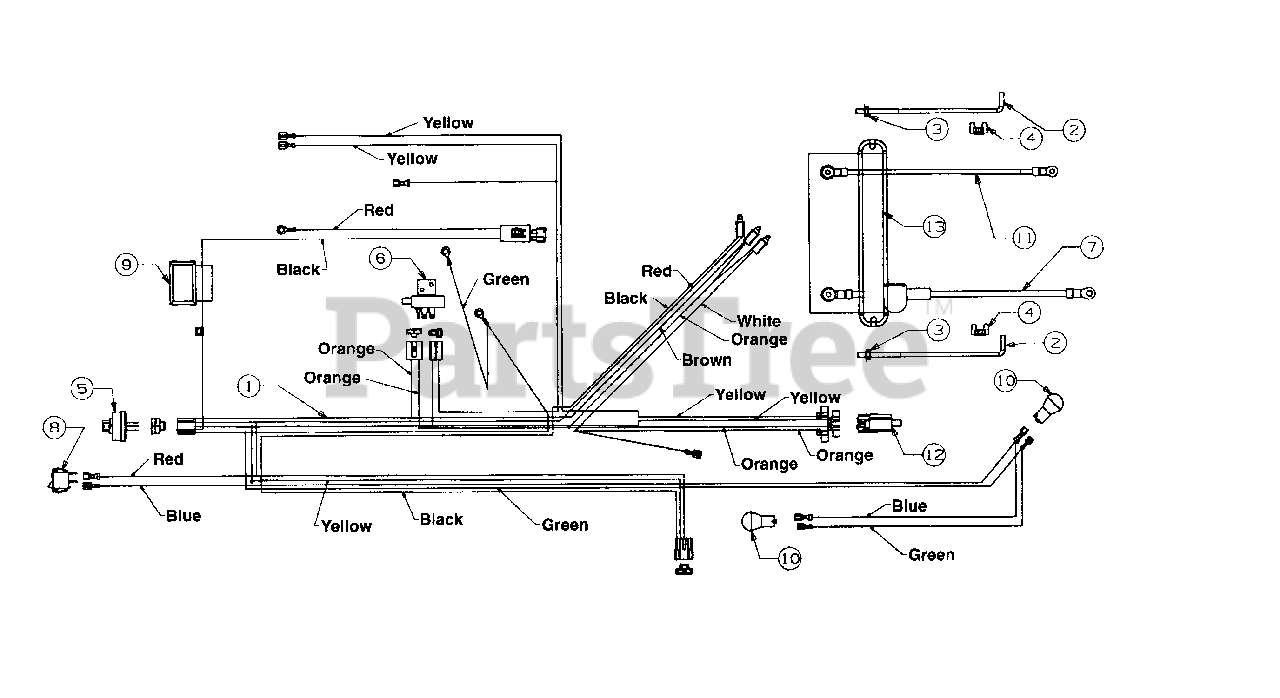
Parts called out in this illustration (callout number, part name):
1	Wire Harness
2	Battery Hold Down Rod
3	Hex L-Nut 1/4-20 Thd.
4	Wing Nut 1/4-20 Thd.
5	Ignition Switch
6	Safety Switch (PTO)
7	Wire w/Boot 14" Lg.
8	Light Switch
9	Ammeter
10	Bulb (Headlight)
11	Wire 12" Lg.
12	Safety Switch (Clutch)
13	Battery Cover
